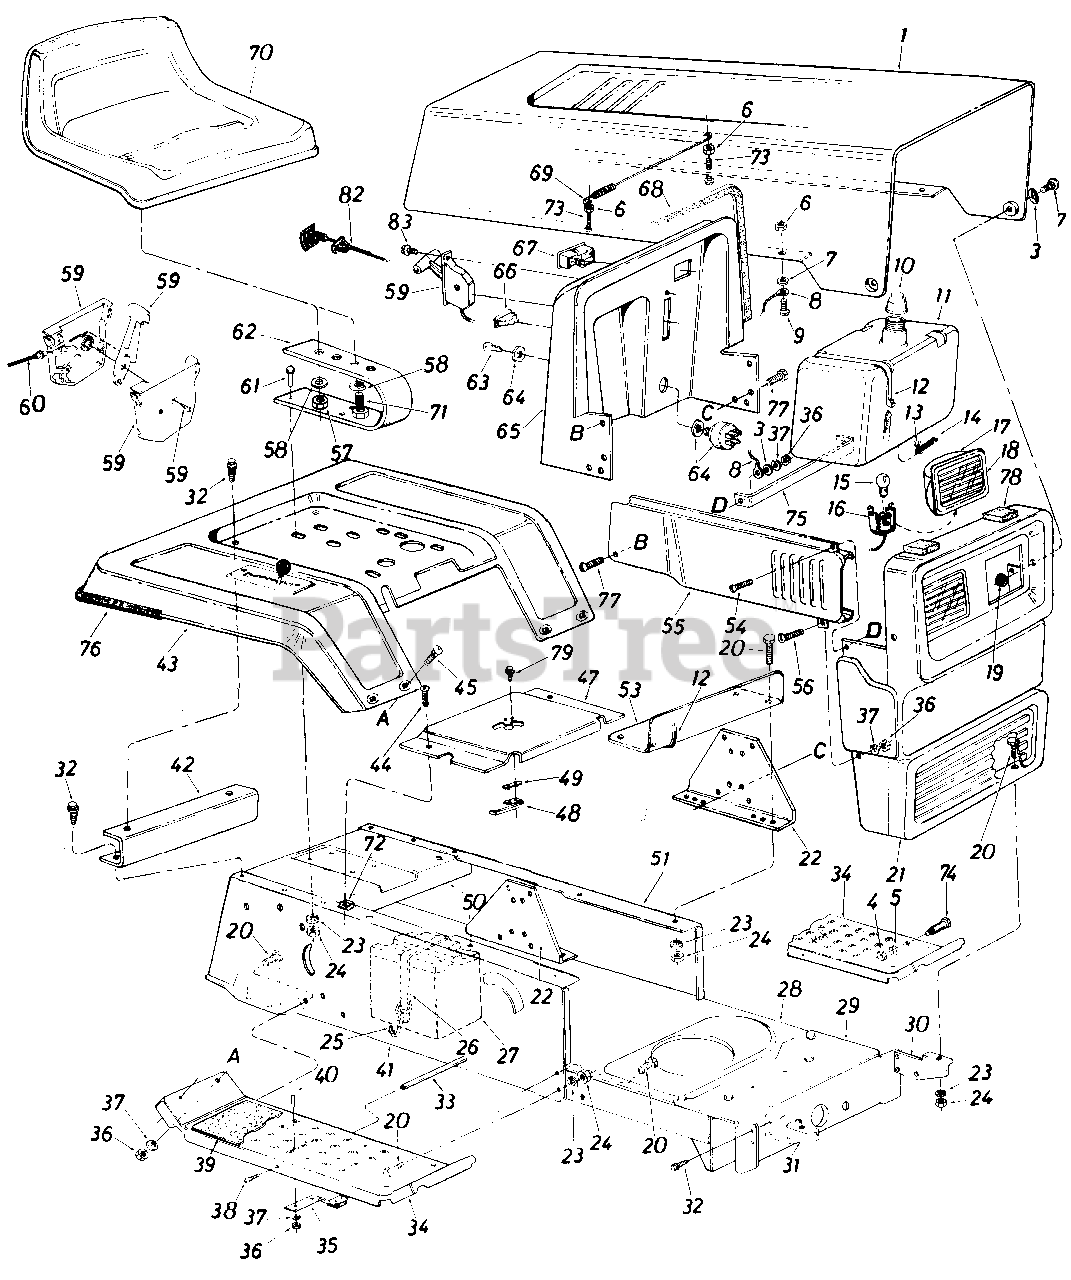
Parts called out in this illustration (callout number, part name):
1	Hood
3	Washer .39" I.D. x .62"
4	Hex Nut 3/8-16 Thd.*
5	L-Wash. 3/8" I.D.
6	Hex Sems Nut #10-24 Thd.
7	Fl-Wash. .203" I.D. x .411' O.D. x .040
8	Hood Stop
9	Truss Hd. Scr. #10-24 x 1/2"*
10	Fuel Cap Gauge
11	Fuel Tank
12	Tie Strap
13	Hose Clamp
14	Fuel Line
15	Lamp
16	Twist Lock-Lamp Socket
17	Headlight Housing
18	Lens
19	L-Nut 1/4-28 Thd.
20	Hex Bolt 5/16-18 x .75" Lg.
21	Grille
22	Dash Support Bracket
23	L-Wash. 5116" I.D.
24	Hex Nut 5/16-18 Thd.
25	Battery Strap Hook
26	Battery Hold Down Strap
27	12V Battery
28	Lower Frame
29	Front Pivot Brk't.
30	Grille Mount Brk't.-L.H.
33	Running Board Rod
34	Running Board
35	Blade Brake Ass'y.
36	Hex Nut 1/4-20 Thd.
37	L-Wash. 1/4" I.D.*
38	Truss Mach. Scr. 5/16-18 x .75" Lg.
39	Foot Pad
40	Carriage Bolt 1/4-20 x .62"*
41	R.H. Side Frame
42	Fender Mount Brace
43	Rear Fender
45	Carriage Bolt 1/4-20 x .50"*
47	Transmission Panel
48	Reverse Safety Switch
49	Insulator Nut Plate
50	Hitch Plate
51	L.H. Side Frame
53	Fuel Tank Support
54	Truss Hd. Scr. 1/4-20 x .75"*
55	Side Cover-R.H.
56	Truss Mach. Scr. 1/4-20 x .50" Lg.*
57	Hex Nut 1/2-13 Thd.*
58	L-Wash. '/2" I.D.*
59	Throttle Control Box Ass'y.
60	Throttle Control Wire
61	Hex Bolt 5/16-18 x 1.0"*
62	Seat Spring 5.5" High
63	Ignition Key
64	Ignition Switch
65	Dash Panel
66	Light Switch
67	Ammeter
68	Trim Strip-27"
69	Hood Spring
70	Seat Ass'y.
71	Hex Bolt 1/2-13 x 1.0" Lg.
72	Speed Nut #10Z
73	Hex Scr. #10-24 x 1.0" Lg.
74	Shld. Bolt .50 Dia. x .84
75	Tie Strap-Grille/Side Panel
76	Trim Strip-81"
77	Hex Wash. Hd. Tap Scr. 1/4 x .75" Lg.
78	Foam Strip 3/8 x 1-1/8" x 11/2" Lg.
79	Hex Wash. Hd. AB-Tap #8 x .50" Lg.
82	Choke Control 29" Lg.
83	Truss Mach. AB-Tap Scr. #10 x .5" Lg.
